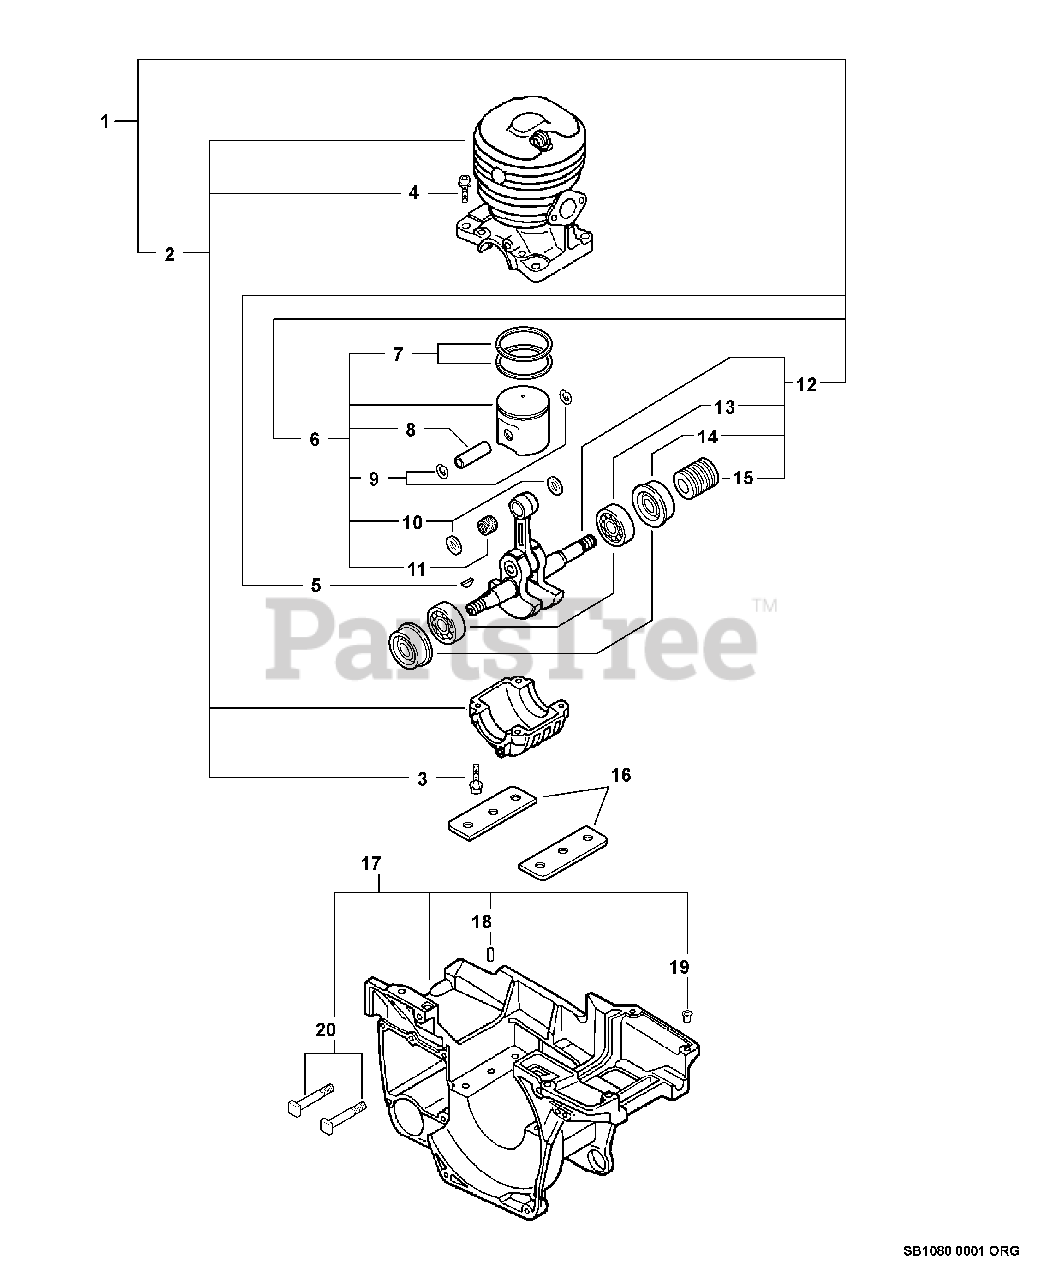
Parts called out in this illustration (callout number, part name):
1	SHORT BLOCK
2	CRANKCASE KIT
3	BOLT 5×20
5	KEY, WOODRUFF
6	PISTON KIT
7	RING, PISTON
8	PIN, PISTON
9	RING, SNAP
10	SPACER
11	BEARING, NEEDLE 11
12	CRANKSHAFT ASSY
13	BEARING, BALL 6202
14	SEAL, OIL
15	GEAR, WORM
16	PLATE, EYE
17	COVER ASSY, ENGINE
18	PIN, LOCATING 4×8
19	COLLAR 5.5×6.65×5
20	STUD, GUIDE BAR 8
